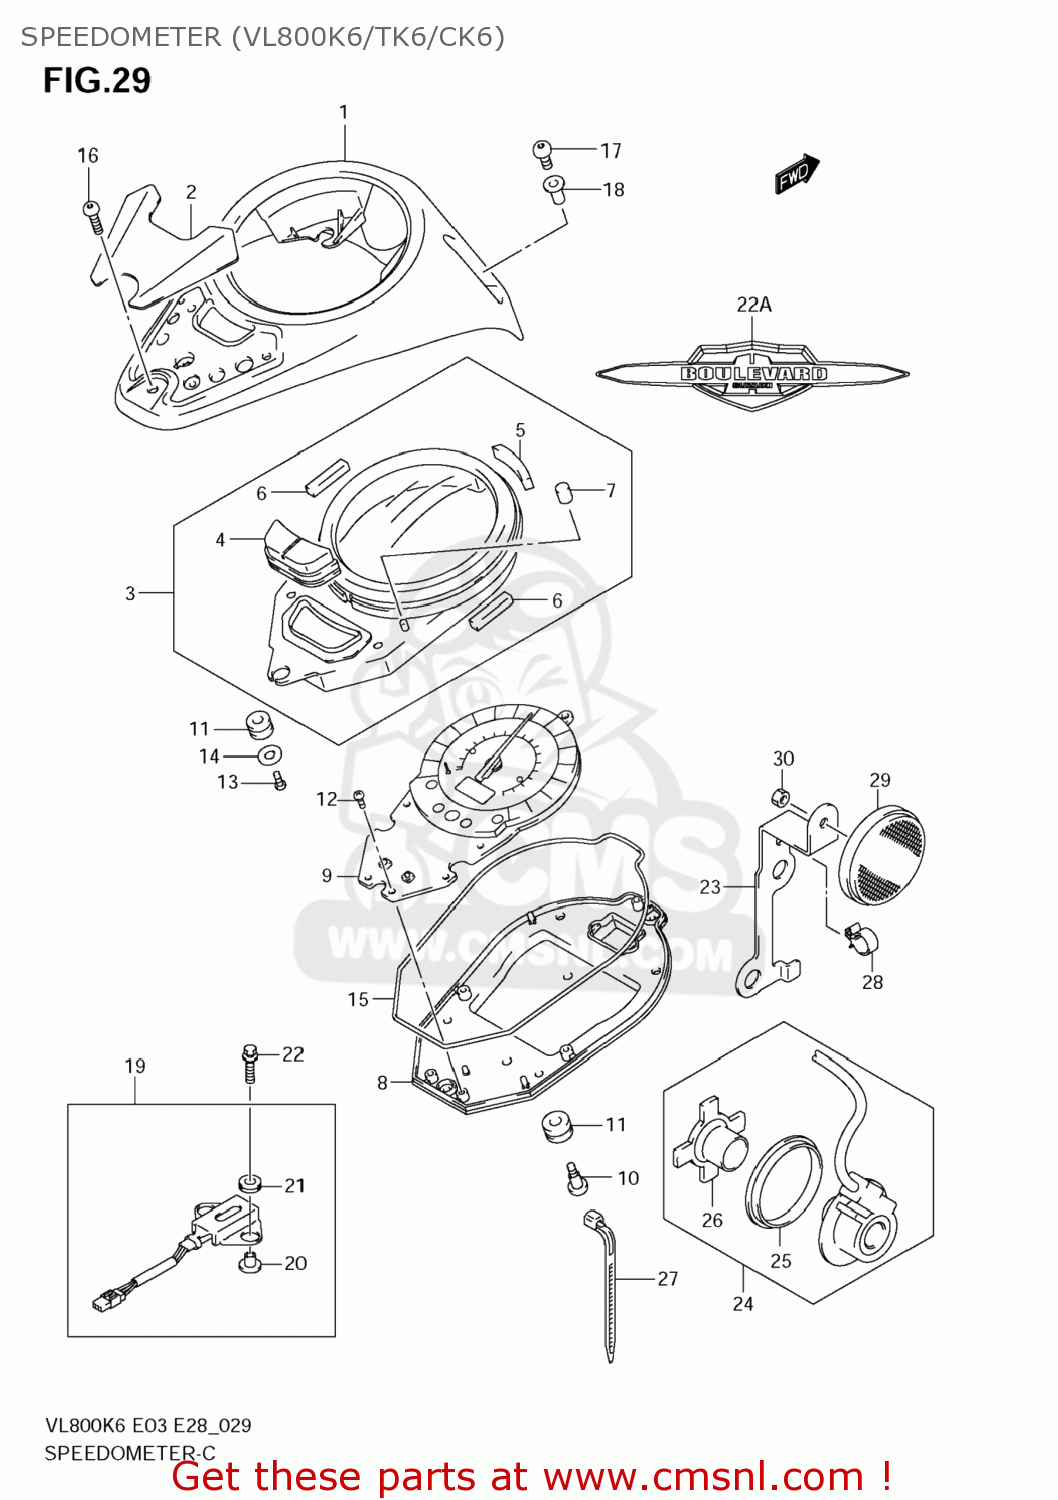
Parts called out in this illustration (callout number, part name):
1	CASE ASSY
2	PLATE,DECORATION
3	CASE,UPR
4	SWITCH,SELECT
5	CUSHION NO.1
6	CUSHION NO.2
7	CUSHION NO.4
8	CASE,LWR
9	SPEEDOMETER
10	BOLT
11	CUSHION,METER
12	SCREW(3X10)
13	SCREW(4X14)
14	WASHER
15	GASKET,METER CASE (NAS)
16	SCREW(5X14)
17	SCREW(5X18)
18	NUT
19	RESISTOR ASSY
20	SPACER(6.5X10X11.6)
21	CUSHION
22	BOLT(6X25)
22A	EMBLEM,BOULEVARD
23	GUIDE,SPEED SENSOR LEAD
24	SENSOR,SPEED
25	SEAL,OIL(44X55X6)
26	MAGNETO
27	CLAMP(L:145)
28	CLAMP
29	REFLECTOR,REFLEX FR
30	NUT
